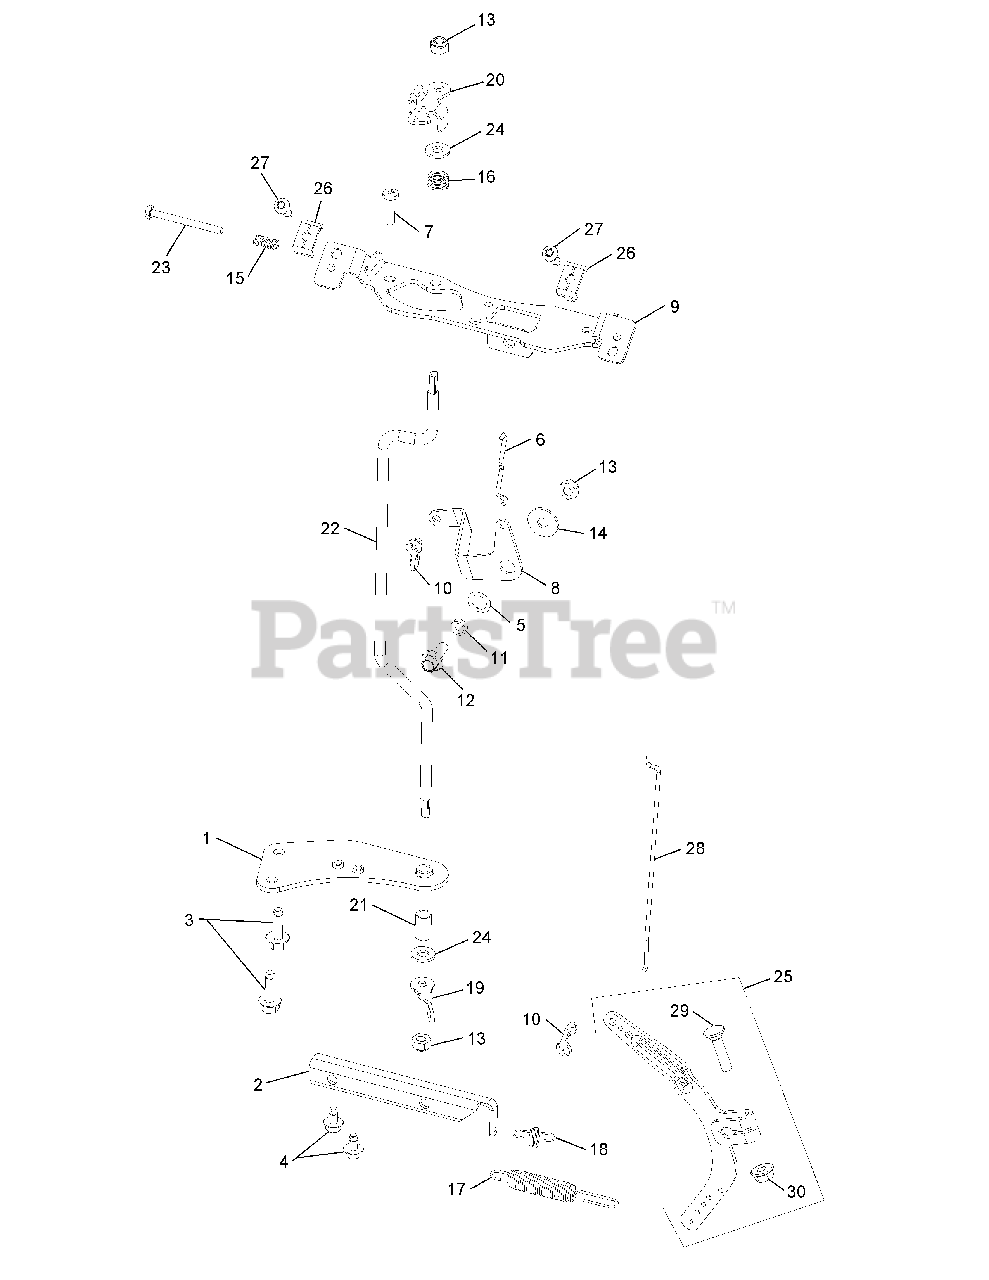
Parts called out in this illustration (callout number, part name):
1	Throttle Shaft Bracket
2	Governed Idle Bracket
3	Thread Forming Screw
4	Thread Forming Screw
5	Spring Washer, 3/8
6	Choke Linkage
7	Screw, 11-16 x 3/4
9	Control Bracket
10	Throttle Linkage Bushing
12	Flange Screw, M6 x 1.0 x 16
13	Lock Nut, M6 x 1.0
14	Flat Washer, 1/4
15	Speed Control Spring
16	Throttle Shaft Spring
17	Governor Spring
18	Governed Idle Spring
19	Throttle Control Lever
20	Throttle Control Lever
22	Control Shaft
23	Hex Head Screw
24	Flat Washer, 1/4
25	Governor Lever
27	Thread Forming Screw
28	Throttle Linkage
29	Bolt, M6 x 1.0 x 25
30	Flange Nut, M6 x 1.0
